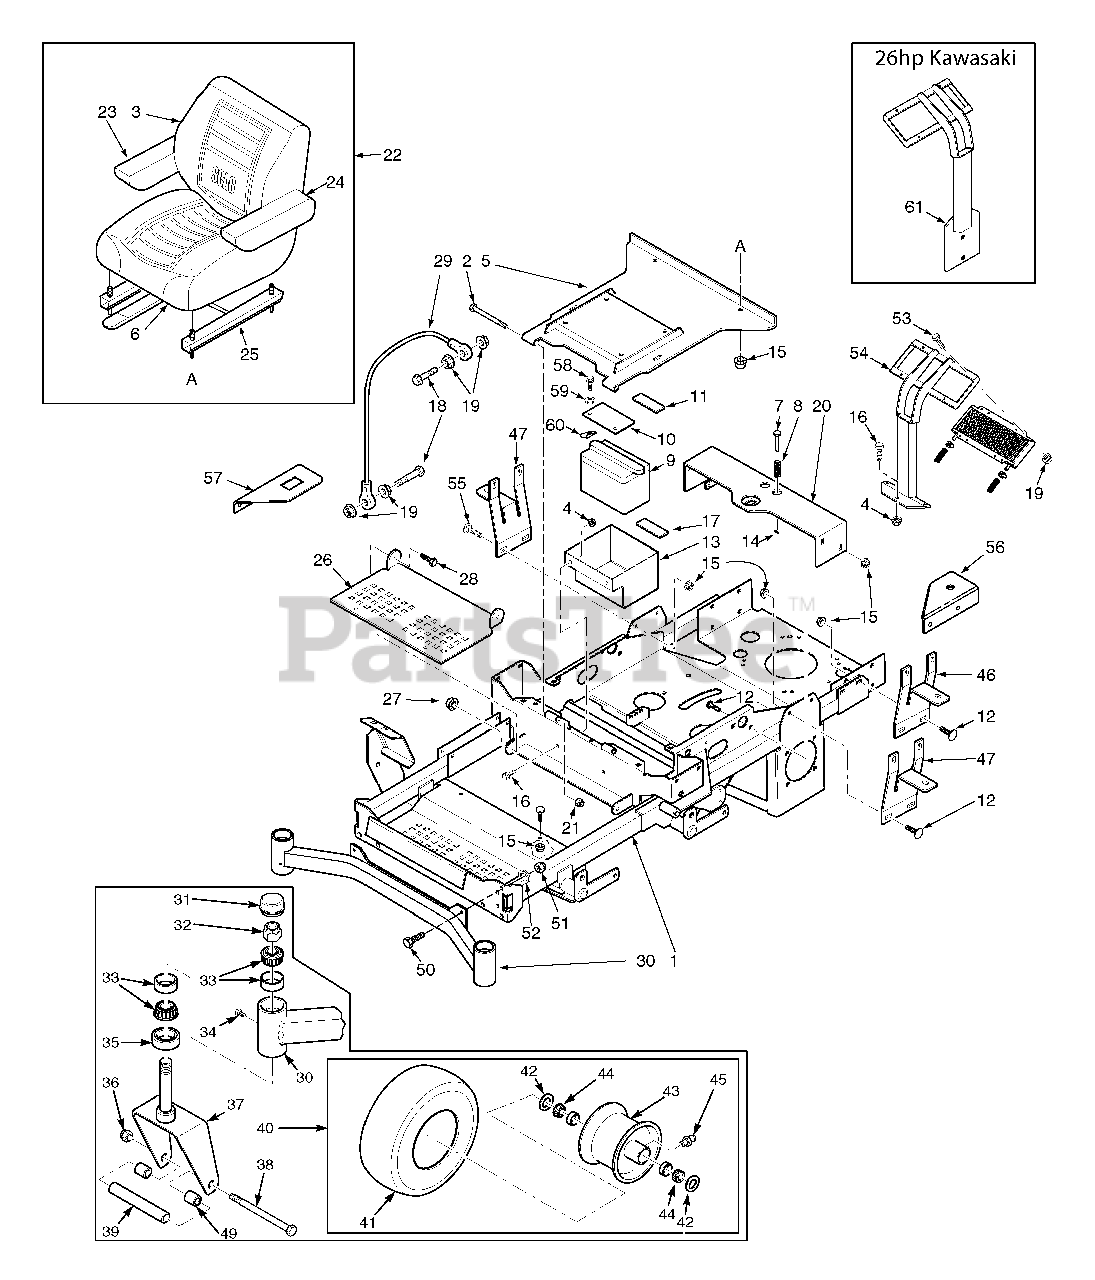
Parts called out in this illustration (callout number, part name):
1	Main Frame Assembly w/decals
2	Bolt, Hex Head 5/16-18 x 3-3/4"
3	Back Cover
4	Nut, Serr. Flange 3/8-16
5	Plate, Seat Mounting
6	Cushion Cover
7	Pin Retainer, Spring
8	Spring
9	Battery
10	Battery Cover
11	Battery Hold Down Pad
12	Bolt, Carr. 5/16-18 x 3/4"
13	Battery Box
14	Roll Pin, Spring 5/32 x 3/4"
15	Nut, Serr. Flange 5/16-18
16	Bolt, Hex Head 3/8-16 x 1"
17	Pad, Rubber
18	Bolt, Hex Head 1/4-20 x 1-1/4"
19	Nut, Serr. Flange 1/4-20
20	Seat Base Support
21	Nut, Elastic Stop 5/16-18
22	Seat Assembly w/ adj. rails
23	Armrest Cover
24	Armrest Cover
25	Seat Track Set
26	Footplate
27	Nut, Elastic Stop 3/8-16
28	Bolt, Hex Head 3/8-16 x 1"
29	Cable, Seat Stop
30	Weldment, Caster Support (61V)
31	Cap, Grease
32	Nut, Elastic Stop 1.0-14
33	Bearing Set
34	Plug, 1/4-28
35	Seal, 2.0" OD x 1.625" ID
36	Nut, Elastic Stop 1/2-13
37	Yoke, Front Caster Wheel
38	Bolt, Hex Head 1/2-13 x 9-1/2"
39	Sleeve
40	Caster Wheel Assembly
41	Tire, 13 x 6.5 Smooth
43	Rim
44	Roller Bearing
45	Fitting, Grease
46	Mounting Bracket, Oil Tank
47	Mounting Bracket, Fuel Tank
48	Seat Pan
49	Spacer, Caster Wheel
50	Bolt, Hex Head 7/16-14 x 1-1/4"
51	Nut, Elastic Stop 7/16-14
52	Lockwasher, 7/16
53	Bolt, Hex Head 1/4-20 x 5/8"
54	Support Weldment, Oil Cooler
55	Bolt, Carriage 5/16-18 x 1"
56	Bracket, Fuel Valve
57	Bracket, Hour Meter
58	Bolt, Hex Head 3/8-16 x 1-1/4"
59	Lock Washer. 3/8 Spring
60	U-Nut, 3/8-16
61	Support Weld, Oil Cooler - 26hp Kaw.
